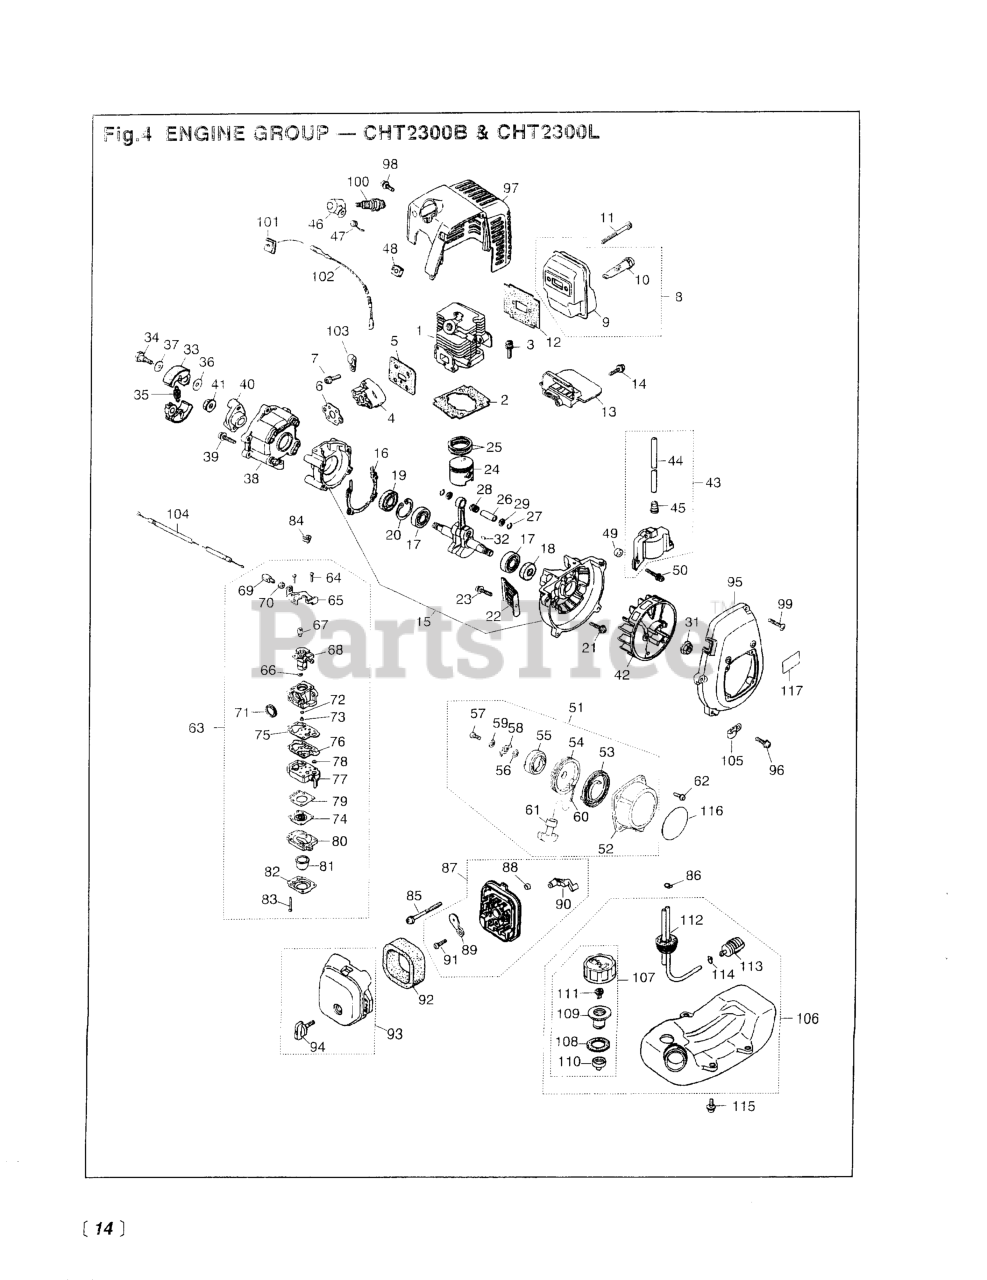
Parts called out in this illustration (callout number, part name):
1	CYLINDER
3	BOLT, M5 X 22
7	SCREW, M5X20 (RPLS.1400-75510)
8	MUFFLER ASSEMBLY
10	ARRESTER (RPLS 5850-15140)
11	BOLT, M5 x 50
12	GASKET, MUFFLER
14	SCREW, M4 X 16
15	CRANKCASE COMP.
17	BEARING
18	SEAL, OIL (RPLS 1100-21210)
19	SEAL, OIL (RPLS 1140-21220)
20	RING, SNAP, M28 x 1.2
21	BOLT, M5 X 30
23	SCREW,M5 X 14 (RPLS 1400-15510
24	PISTON (REPLACES 1140-41110)
25	RING, PISTON (RPLS 1850-41210)
26	PIN, PISTON 5x8x26
27	RING, SNAP (RPLS 1101-41320)
29	WASHER
30	CRANKSHAFT (RPLS -42000)
32	KEY
33	SHOE (RPLS 1100-51114)
34	BOLT
35	SPRING, CLUTCH (RPLS-51220)
36	WASHER, FLAT (USE 182303)
38	CASE, CLUTCH
39	SCREW
40	PLATE, CLUTCH
42	ROTOR (RPLS 5601-71110)
44	CORD
45	CAP
47	SPRING
48	GROMMET
49	SPACER (RPLS -71260)
50	BOLT
52	CASE, RECOIL
53	SPRING, SPIRAL
56	WASHER
57	SCREW
58	RETAINER (RPLS 1861-75161)
59	WASHER
60	ROPE
62	SCREW, M4 x 12
63	CARBURETOR (WYJ-114-1)
64	SCREW
65	BRACKET
66	RING
67	SWIVEL
68	VALVE ASSY
69	SCREW, CABLE ADJUSTER
70	NUT, CABLE ADJUSTER
71	RING, PACKING
72	RING, O
74	DIAPHRAGM (USE 4810-81260)
75	GASKET, PUMP
76	DIAPHRAGM
77	BODY, PUMP
79	GASKET, DIAPHRAGM
80	BODY, PURGE
81	PUMP, PRIMING
82	COVER, PUMP
83	SCREW
84	CAP, CABLE END
85	SCREW, M5 x 60
86	CLIP
88	SLEEVE
89	PLATE, CHOKE (RPLS-82130)
90	LEVER, CHOKE
91	SCREW (REPLACES 50030272)
92	ELEMENT
95	COVER, FAN
96	SCREW, M5X20 (RPLS.1400-75510)
97	COVER, ENGINE(USE-32101)
98	SCREW, M5 x 12
99	SCREW, HOUSING
102	CORD
103	CLAMP
104	CABLE
105	CLAMP
108	PACKING
110	HOLDER, CAP
111	VALVE (NLA WHEN OUT)
112	PIPE COMPLETE
113	FILTER ASSY
114	CLIP (REPLACES 2841-31280)
115	SCREW
